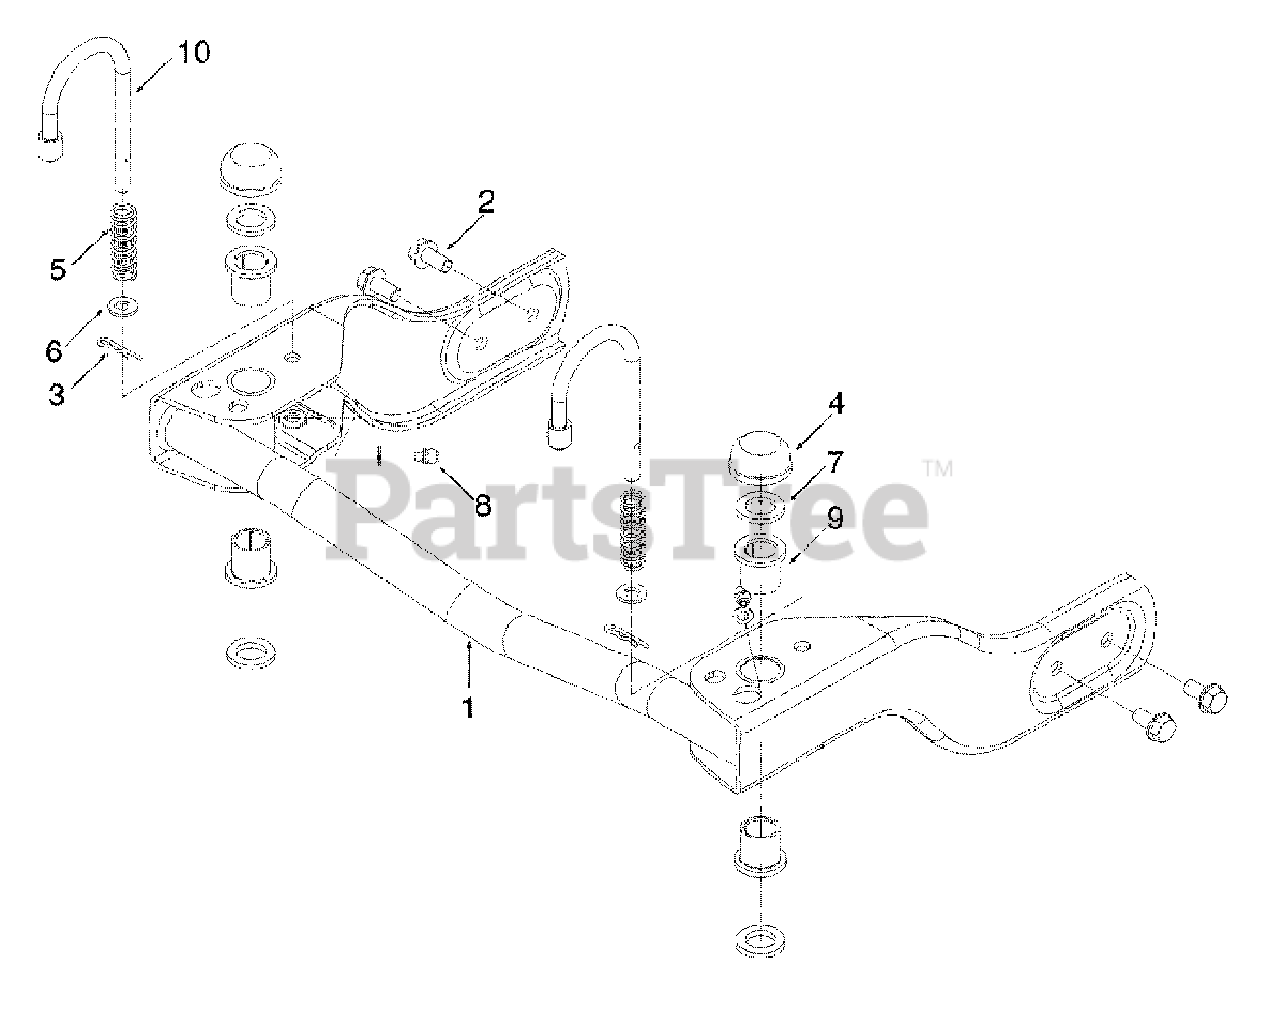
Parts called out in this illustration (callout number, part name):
2	HEX WASH HD TT-TAP SCR. 5/16-18 x .62 LG
3	INTERNAL COTTER PIN .072 x 1.75 LG
4	PUSH CAP 5/8
5	COMPRESSION SPRING .406 x .531 x 1.75 LG
6	FLAT WASHER .330 ID x .630 x .06
7	FLAT WASHER 5/8 ID 1.00 OD
8	FITTING 3/16
9	FLANGE BEARING .632 ID
10	LOCK PIN / FRONT WHEEL
